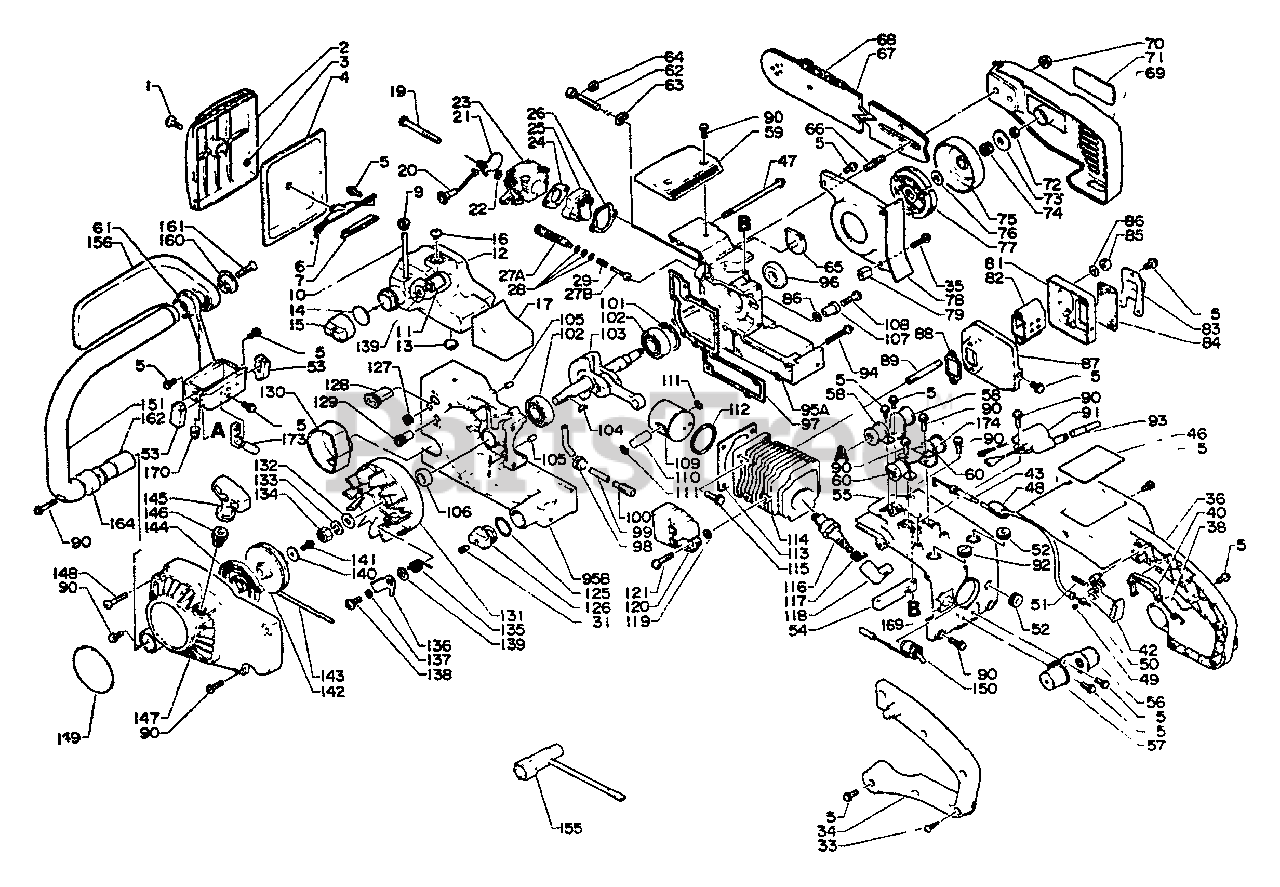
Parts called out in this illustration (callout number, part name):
1	THUMBSCREW
2	COVER, AIR FILTER
3	E-RING 3
4	FILTER, AIR
5	SCREW 4×10
6	BRACKET, AIR FILTER
7	CUSHION
9	GROMMET
10	FUEL PIPE KIT
11	FILTER, FUEL
12	TANK, FUEL
14	GASKET
15	CAP
16	VALVE, CHECK
17	CUSHION
19	SCREW 5×50
20	ROD, CHOKE
21	SHUTTER, CHOKE
22	WASHER 5.5×8×0.8
23	CARBURETOR - C1S-K1B
24	GASKET, INTAKE
25	INSULATOR
26	GASKET, INTAKE
27	PUMP KIT
27A	PUMP KIT
27B	PUMP KIT
31	VENT ASSY
33	SCREW - 4×16 -- TAPPING
34	HANDLE, REAR
35	SCREW 4×20
36	HANDLE, REAR
38	SPRING
40	LOCKOUT, THROTTLE
42	TRIGGER, THROTTLE
43	CABLE, THROTTLE
46	LABEL
48	GROMMET
49	SCREW, SET
51	SPRING, THROTTLE
54	SPACER
55	COVER, CYLINDER
56	CUSHION
57	CUSHION
59	COVER, INTAKE
60	CUSHION (U)
61	SUPPORTER
62	SCREW, TENSIONER
63	TENSIONER
65	PLUG
66	BOLT, STUD
67	GUIDE BAR - 14"
68	SAWING CHAIN - 91SG-52E
69	GUARD, SPROCKET
70	NUT - 6 -- FLANGE
71	LABEL - ECHO
72	LOCKNUT - 6
74	BEARING, NEEDLE 8
75	DRUM, CLUTCH - 3/8"
76	WASHER, CLUTCH
77	CLUTCH ASSY
78	PLATE, SEAL
79	SPACER
81	COVER
82	SILENCER
83	COVER, MUFFLER
84	SCREEN, SPARK ARRESTER
85	LOCKNUT - 5
86	WASHER 5.3×10×1
88	GASKET, EXHAUST
89	BOLT, STUD
90	SCREW 4×16
91	COIL, IGNITION
93	PIPE
94	SCREW 4×30
95	CRANKCASE
95A	CRANKCASE
95B	CRANKCASE
96	SEAL, OIL
97	GASKET, CRANKCASE
98	GROMMET
99	PIPE, OIL
100	FILTER, OIL
101	RING, SNAP Ø32
102	BEARING, BALL - 6201 C3
103	CRANKSHAFT
105	PIN, LOCATING 4
106	SEAL, OIL
107	CATCHER, CHAIN
108	SCREW 5×20
109	PISTON
110	PIN, PISTON
111	RING, SNAP
112	RING, SNAP
113	GASKET, CYLINDER
114	CYLINDER
115	SCREW 5×20
116	SPARK PLUG - CJ-8Y
117	TERMINAL, SPARK PLUG CAP
118	CAP, SPARK PLUG
119	SPACER
120	COIL, IGNITION
121	SCREW 5×22
125	O-RING 16 MM
126	CAP, OIL TANK
127	GROMMET, CHOKE
128	GROMMET
129	GROMMET
130	SEAL
131	FLYWHEEL
132	WASHER 8.5×16×1.2
133	WASHER, SPRING 8
134	NUT 8×1.25
135	SPRING, RETURN
136	RATCHET
137	SPACER 5.2×8×2.1
138	SCREW
139	WASHER 5.5×12×0.8
140	WASHER 4.1×15.5×1T
141	SCREW - 4×10
142	REEL, ROPE
143	ROPE, STARTER 3.0×850
144	SPRING, RECOIL
146	GUIDE, ROPE
147	COVER, FAN
148	SCREW 4×25
149	LABEL - ECHO
150	SWITCH
151	HANDLE, FRONT
155	T-WRENCH 10×19 MM
156	GUARD
160	HOLDER, GUARD
161	SCREW 5×25
162	CUSHION
169	LABEL - SWITCH
170	CUSHION, RUBBER
